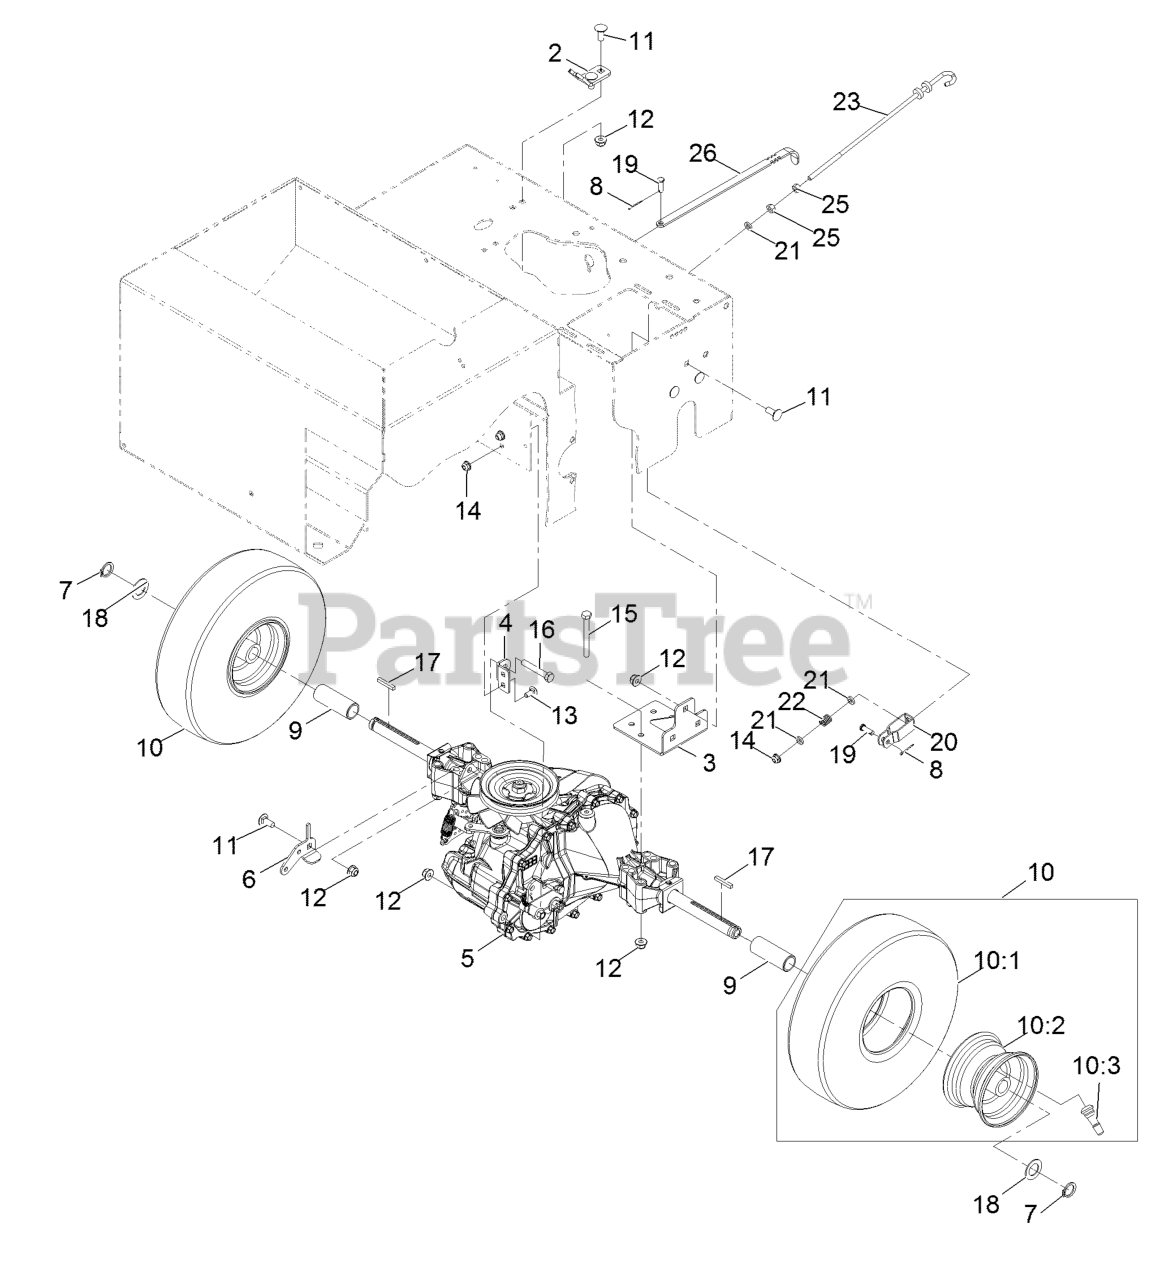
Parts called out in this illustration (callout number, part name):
2	Bracket-Cable
3	Bracket-Axle
4	Bracket-Transaxle, Torque
5	Transaxle ASM
6	Bracket-Transaxle
7	Ring-Retaining
8	Pin-Cotter
10	Wheel ASM
10:2	Wheel-Rim
10:3	Valve
11	Bolt-Carriage 5/16-18 X 3/4 Short Neck
12	Nut-Nyloc 5/16-18 Flg
13	Bolt-Carriage 1/4-20 X 5/8
14	Nut-Nyloc 1/4-20 Flg
15	Screw-HH 5/16-18 X 2 3/4
16	Screw-HH 5/16-18 X 2
17	Key-Machine 3/16 X 3/16 X 1 1/4
19	Pin-Clevis 1/4 X 3/4
22	Spring-Compression
23	Rod-Brake
25	Nut-Hex 1/4-20
26	Lever-Bypass
